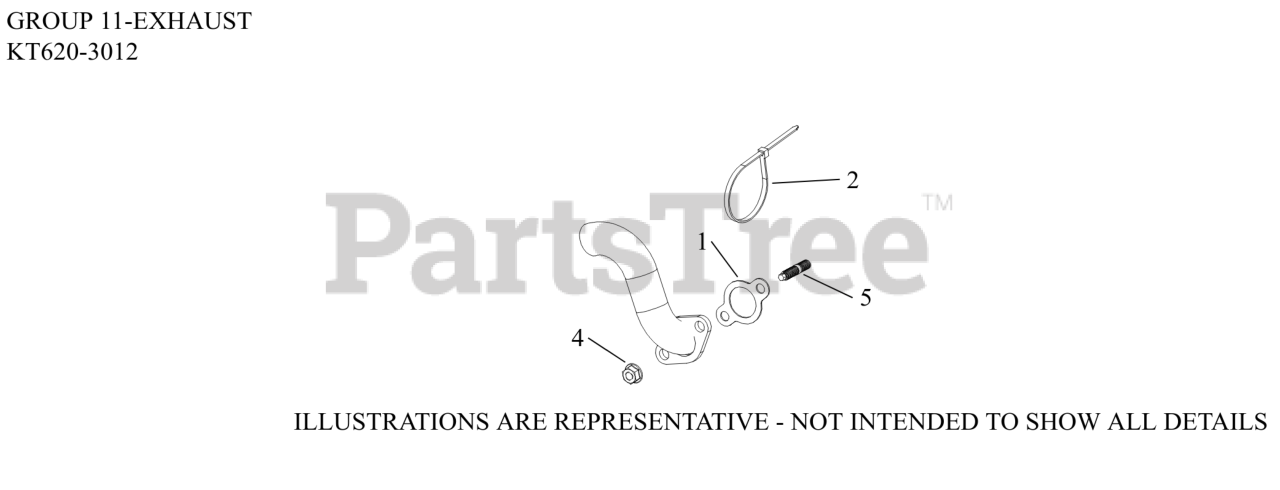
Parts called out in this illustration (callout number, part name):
1	GASKET, EXHAUST
4	NUT, HEX FLANGE LOCK (M8)
5	STUD, EXHAUST
